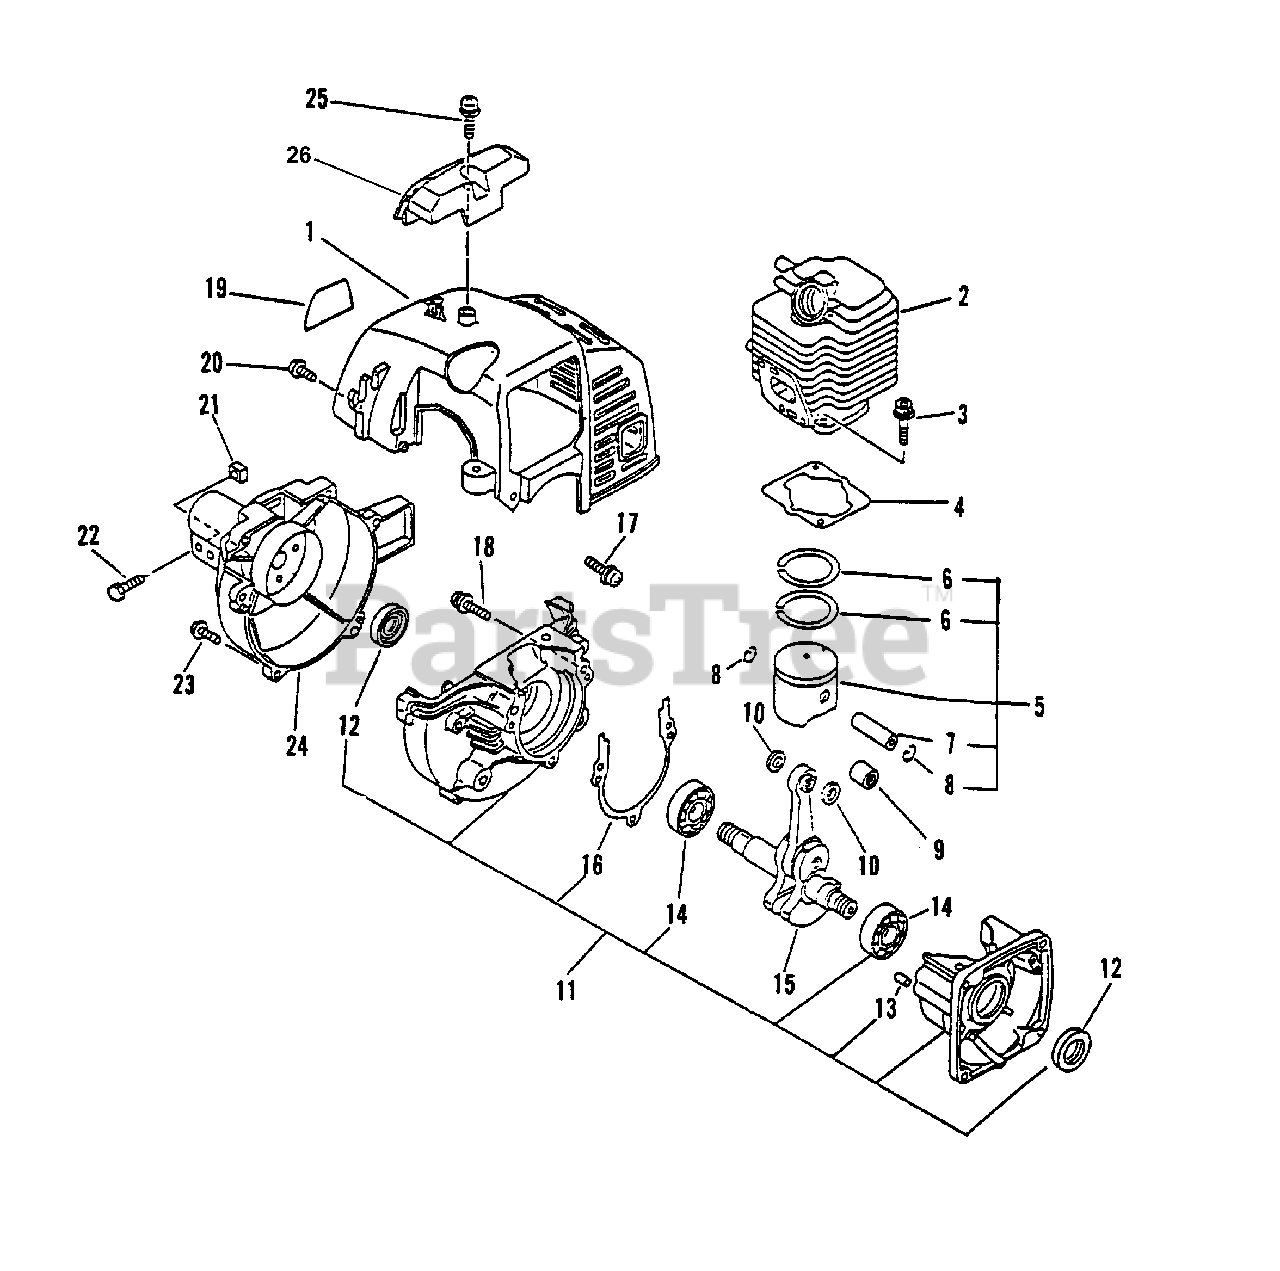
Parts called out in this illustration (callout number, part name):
1	COVER, ENGINE - GRAY
2	CYLINDER
3	BOLT 5×22
4	GASKET, CYLINDER
5	PISTON KIT
6	RING, PISTON
7	PIN, PISTON 8
8	RING, SNAP
9	BEARING, NEEDLE
10	WASHER, THRUST
11	CRANKCASE KIT
12	SEAL, OIL 12
13	PIN, LOCATING 4
14	BEARING, BALL - 6201 C3
15	CRANKSHAFT ASSY
16	GASKET, CRANKCASE
17	SCREW 4×12
18	BOLT 5×28
19	LABEL - MODEL
20	SCREW 4×16
21	NUT M5
22	BOLT 5×28
23	SCREW 4×18
24	FAN CASE ASSY
25	SCREW 5×16
26	GUARD, TOP - GRAY
